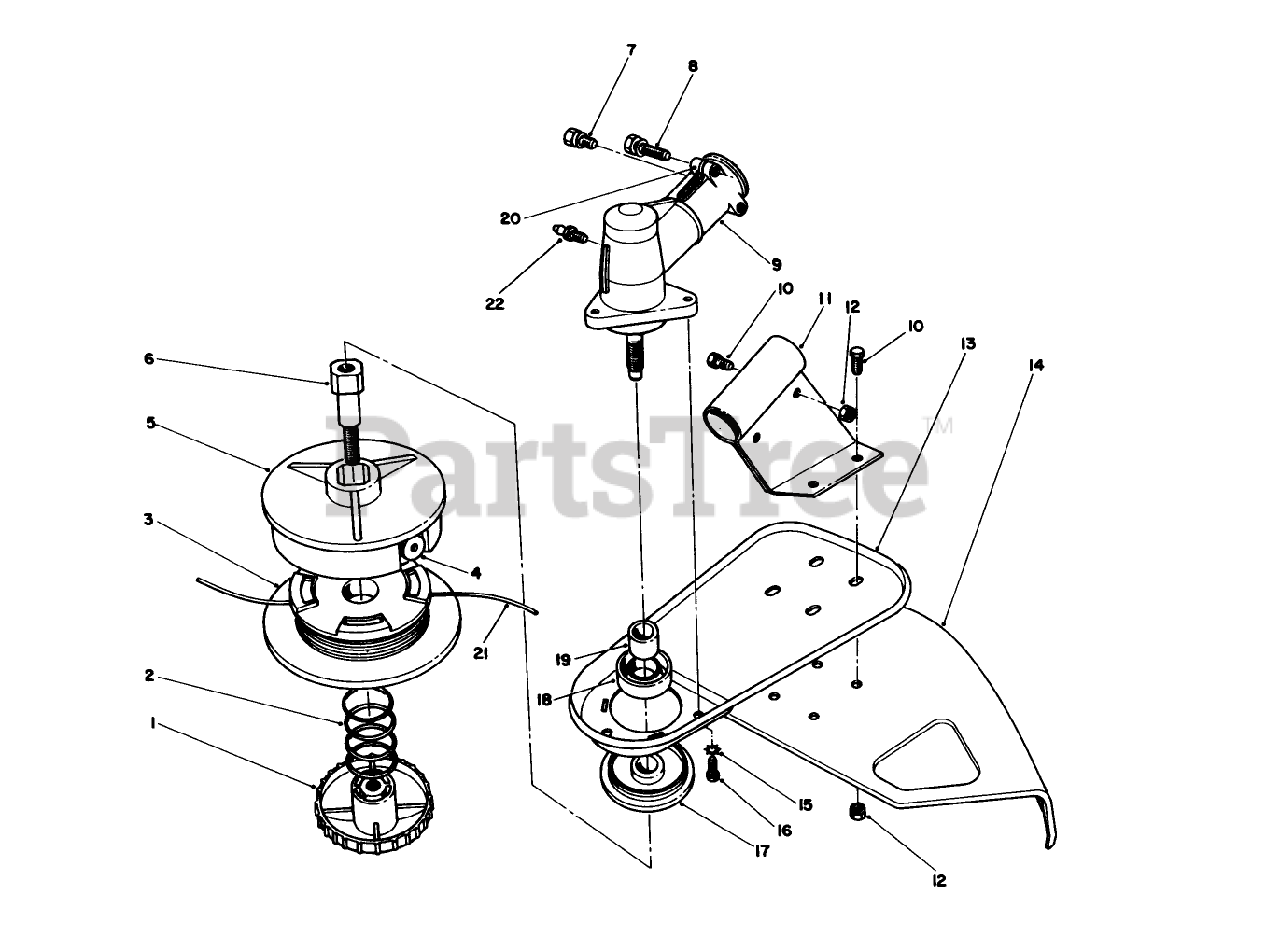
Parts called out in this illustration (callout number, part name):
3	ORDER 57-5670 HEAD
7	HHMS SCREW
9	GEARBOX
10	SCREW-SHH
12	NUT-LOCK, NI
13	SHIELD SUPPORT *R
15	WASHER-LOCK, EXT
16	SCREW
17	DUST CAP F/W
18	OIL SEAL
